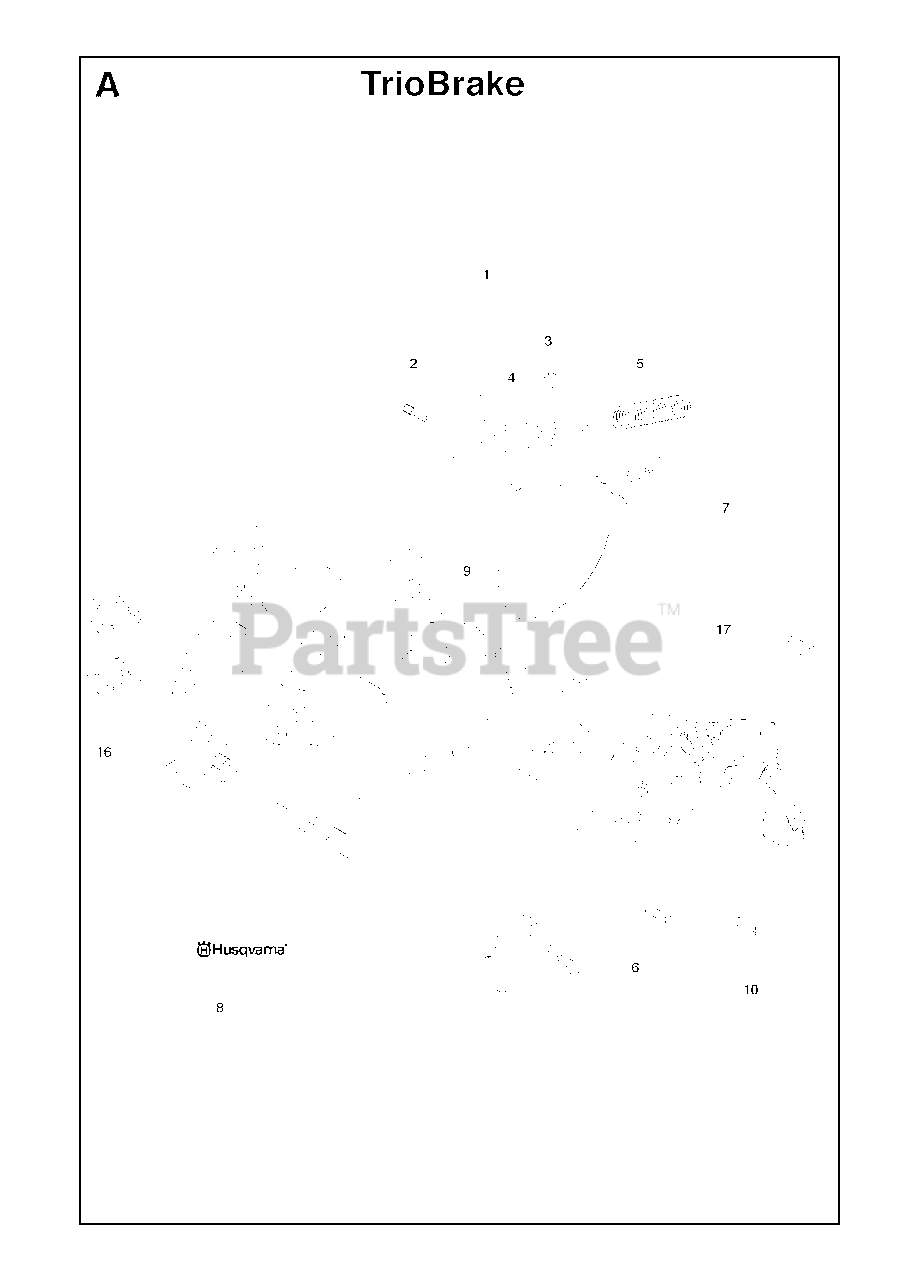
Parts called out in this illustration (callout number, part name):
1	CLUTCH COVER ASSY
1	Clutch Cover Assembly
2	PIN
3	BRAKE BAND ASSY
4	KNEE JOINT ASSY
5	SPRING
6	CHAIN GUIDE
7	BRAKE BAND ASSY
8	LABEL
9	GUARD
10	SCREW
16	NUT RETAINER ASSY
17	COVER LID ASSY
